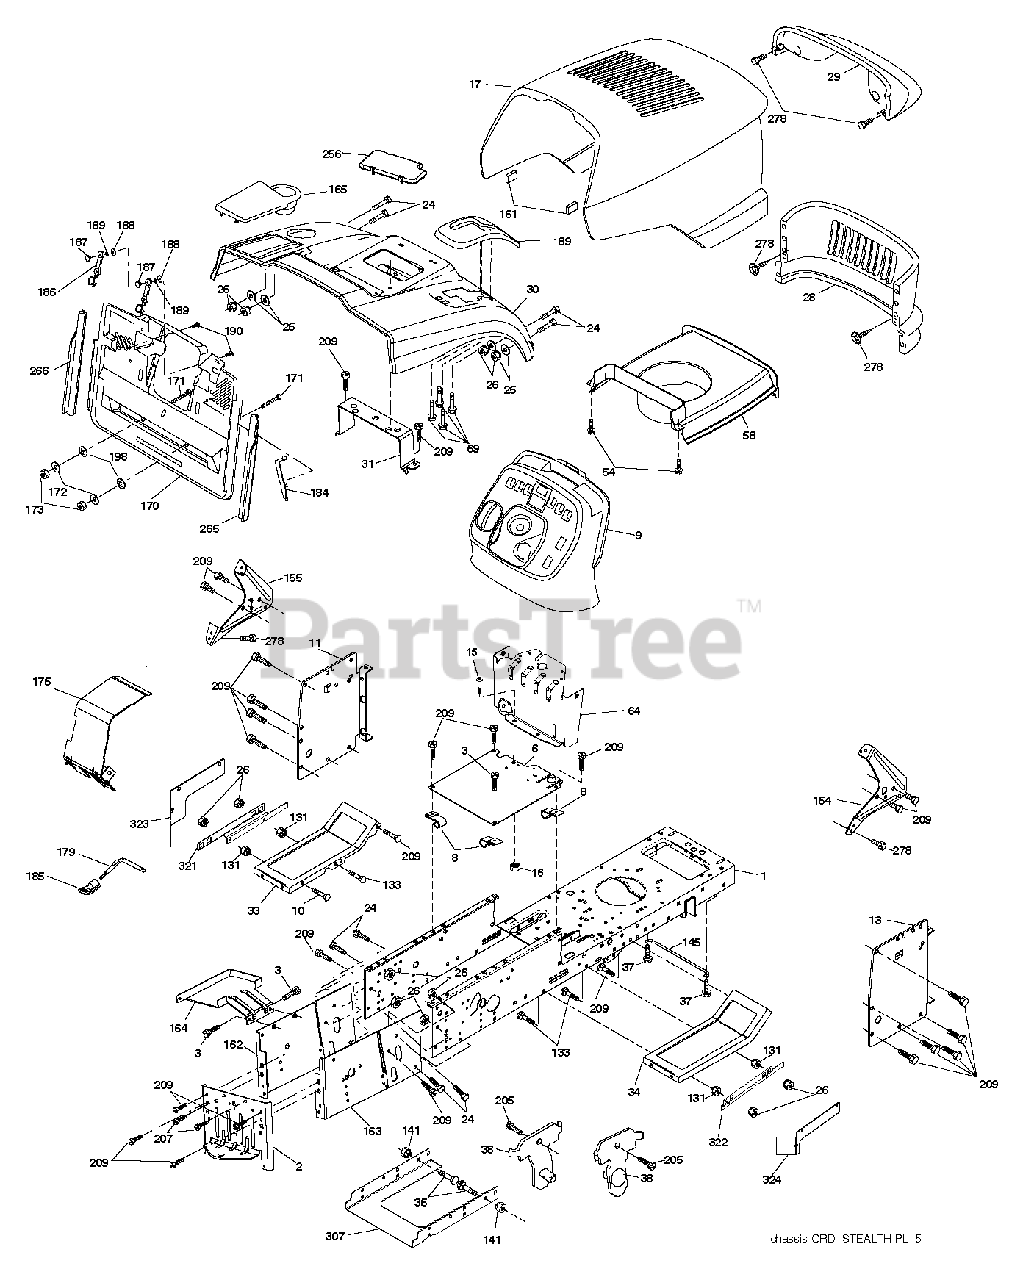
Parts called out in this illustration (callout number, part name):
1	CHASSIS
3	SCREW 3/8-16X3/4
8	CLIP,INSULATOR
10	BOLT.3/8-14X1.25
13	PANEL DASH RH
16	NUT
25	WASHER
26	NUT
31	BRACKET SUPPORT FENDER
54	SCREW.WSHD.HEX10-32X5/8
58	DUCT HOOD
69	SCREW.HI-LO.CONSOLE
131	NUT.HEX.3/8-16UNC
141	NUT LOCK FLG 3/8-16 UNC
145	ROD.PIVOT.HOOD
161	EXTRUSION BUMPER
164	SUPPORT
171	BOLT
172	WASHER
186	LATCH ASSY
187	WELDNUT
189	LOCKWASHER
207	SCREW, 5/16-18 X 1/2
209	SCREW, 3/8-16X3/4
278	SCREW.#10 X 0.750.BOS THREAD
